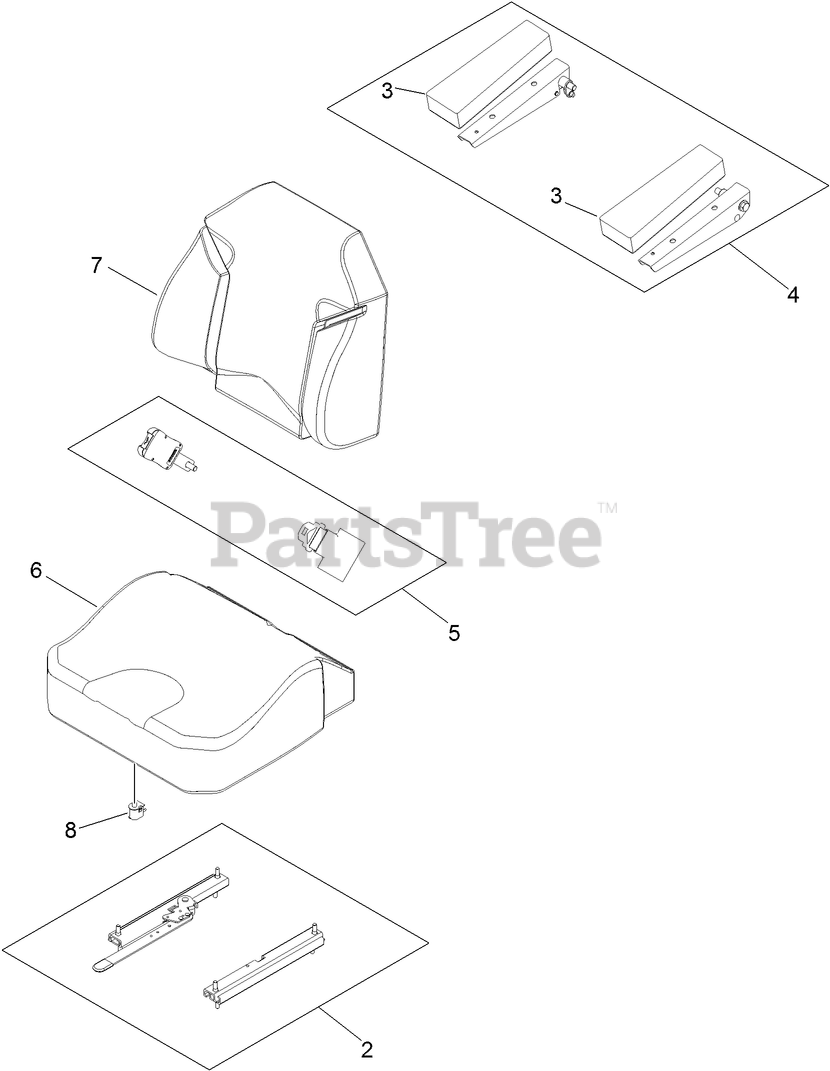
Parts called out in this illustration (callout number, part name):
2	SEAT TRACK SET
3	ARM REST PADS SET
4	ARM REST KIT
5	SEAT BELT KIT
6	COVER-CUSHION
7	COVER-BACK
8	SWITCH-BAIL
